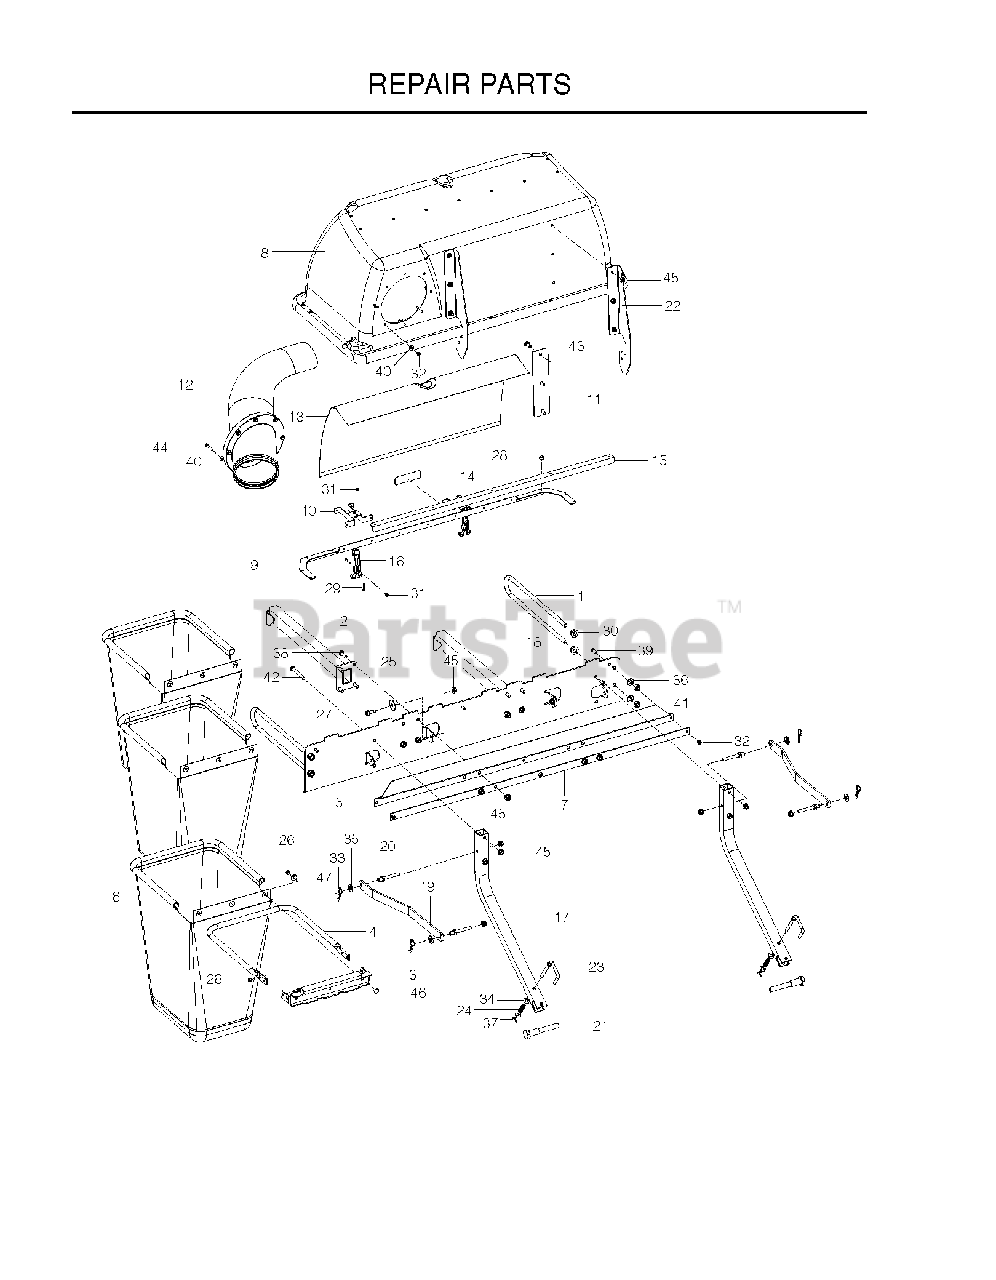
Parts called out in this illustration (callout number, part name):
1	SUPPORT, OUTER
2	SUPPORT ARM WELDMENT
3	HANGER, BAG, BLK
4	TUBE BAG FRAME
5	SEAL, RUBBER
6	BAG, LARGE
7	SEAL STRAP
9	HOOD SUPPORT
10	SUPPORT, DRAW LATCH
11	MOUNT PLATE
12	INLET TUB
13	MESH, POLY DIAMOND
14	DECAL, VENTILATION
15	SUPPORT, HOOD-RR, BLK
16	DRAW LATCH, FLEXIBLE T-HANDLE
17	TUBE, HITCH, BLK
18	PLATE, MOUNT, BLK
19	STRAP, BLK
20	PIN, MOUNT
21	BOLT, PIVOT
22	BRACKET, HINGE, BLK
23	PIN, RETENTION
24	SPRING, COMPRESSION
25	WASHER, FRICTION
26	NUT 5/16 NYLOC
27	BOLT 3/8-16 X 1.0
28	WASHER, #10 MACH SCR BLK OX
29	SCR, #10-24 X 1-1/8
30	NUT 1/2-13 HEX
31	NUT 10-24 NYLOC
32	NUT 1/4-20 NYLOC
33	HAIRPIN #4
34	WASHER 3/8 SAE FLAT
35	WASHER 1/2" FLAT
36	WASHER 1/2" SPLIT LOCK
37	COTTER PIN 1/8 X 3/4
38	HCS 3/8C X 1
39	HCS 1/4C X 3/4 HCS
40	WASHER 1/4 FLAT
41	NUT 1/2 HEX JAM
42	HCS 3/8C X 2 1/4
43	RHSNB 3/8C X 1
44	BOLT 1/4C X 1 3/4
45	NUT 3/8-16 HEX FLG NYLOC ZD
46	BOLT 5/16C X 3/4" CARRIAGE
47	WASHER 5/16 FLAT
